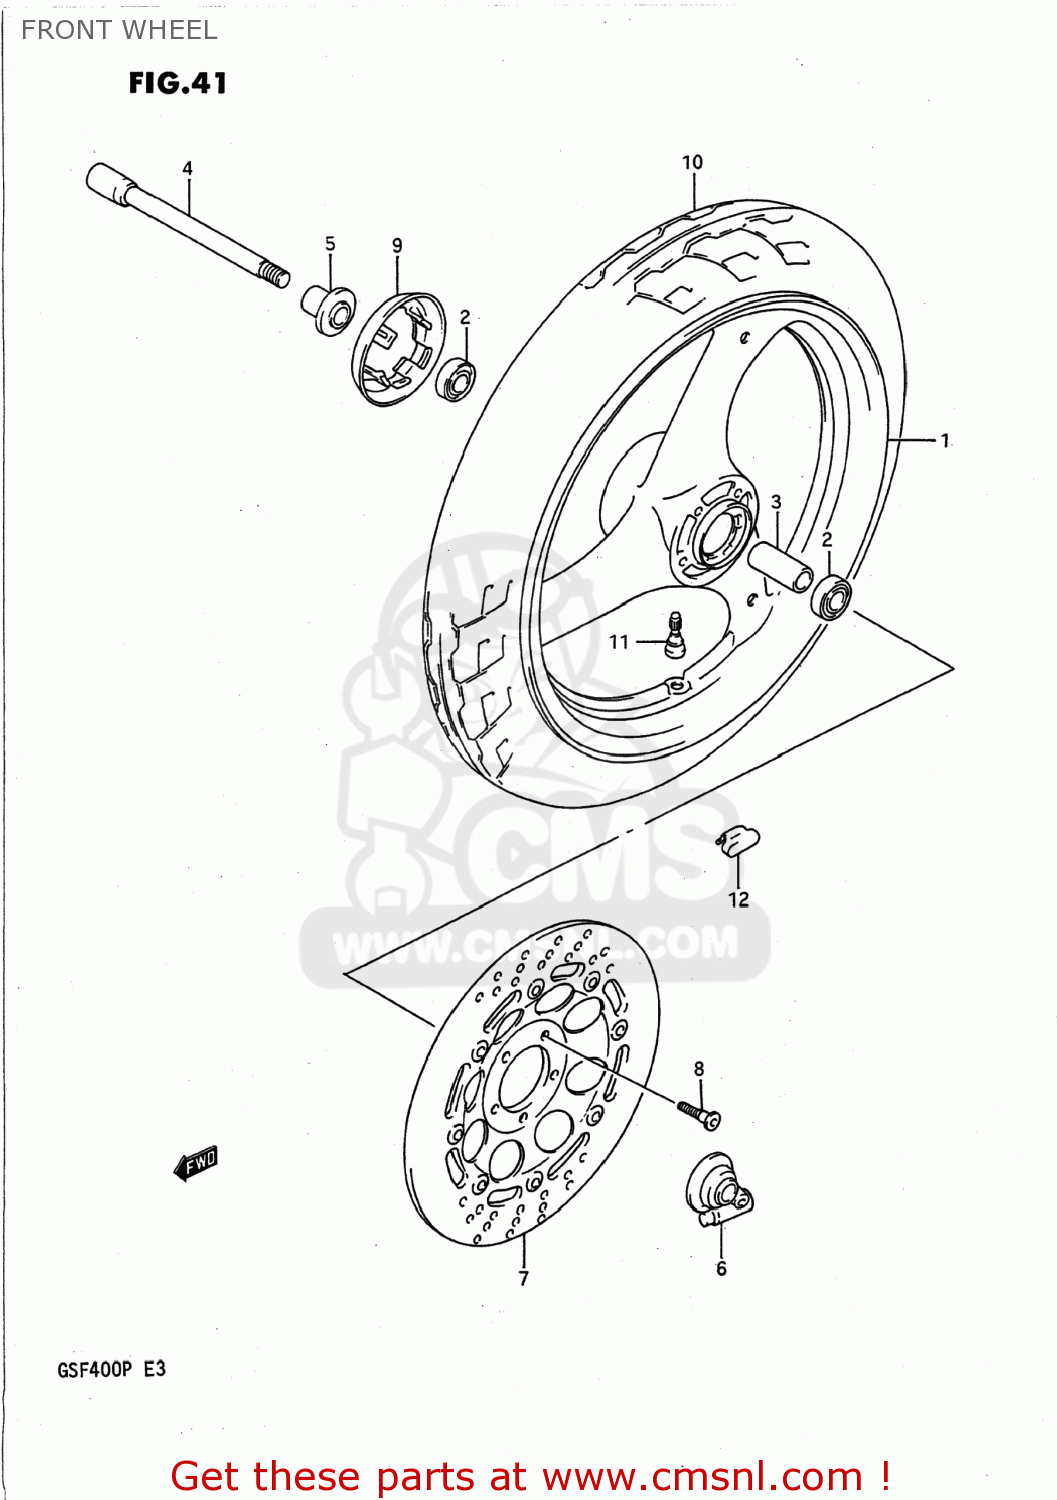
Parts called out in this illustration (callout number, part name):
1	WHEEL,FRONT (17XMT3.00)
2	BEARING
3	SPACER(15.3X21.7X63)
4	AXLE,FRONT
5	SPACER,FR AXLE,R
6	BOX ASSY,SPEEDOMETER GEAR
7	DISC,FR BRAKE,L
8	BOLT 8X33
9	COVER,FR HUB,R
10	TIRE,FR(110/70-17 54H)
11	VALVE ASSY,WHEEL RIM(TR412)
12	BALANCER,WHEEL
